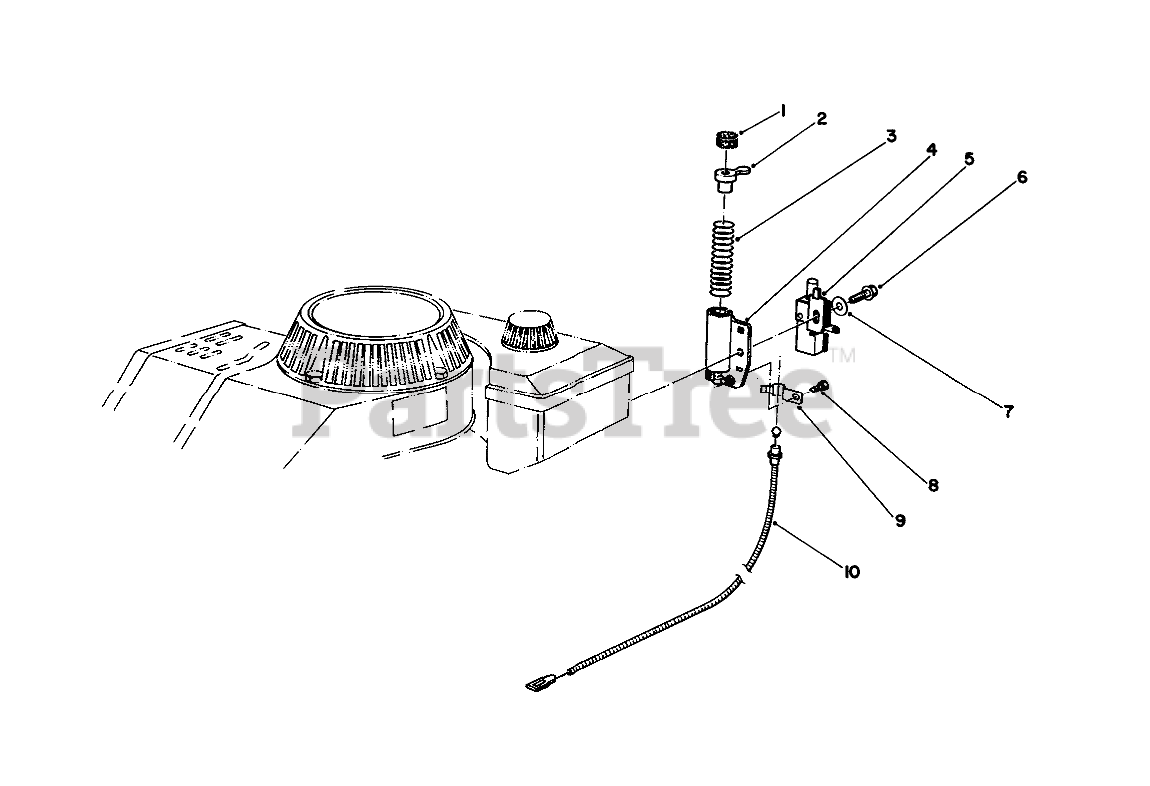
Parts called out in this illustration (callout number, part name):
1	Pad-Friction
2	Plunger & Pad Assembly (Incl. Ref. #1)
3	COMP SPRING
4	TUBE W A
5	PUSH BUTTON SWITCH
6	THO FORM SCREW M6 X 1
7	WASHER-FLAT
8	SCREW
9	CABLE CLAMP
10	BRAKE CABLE
